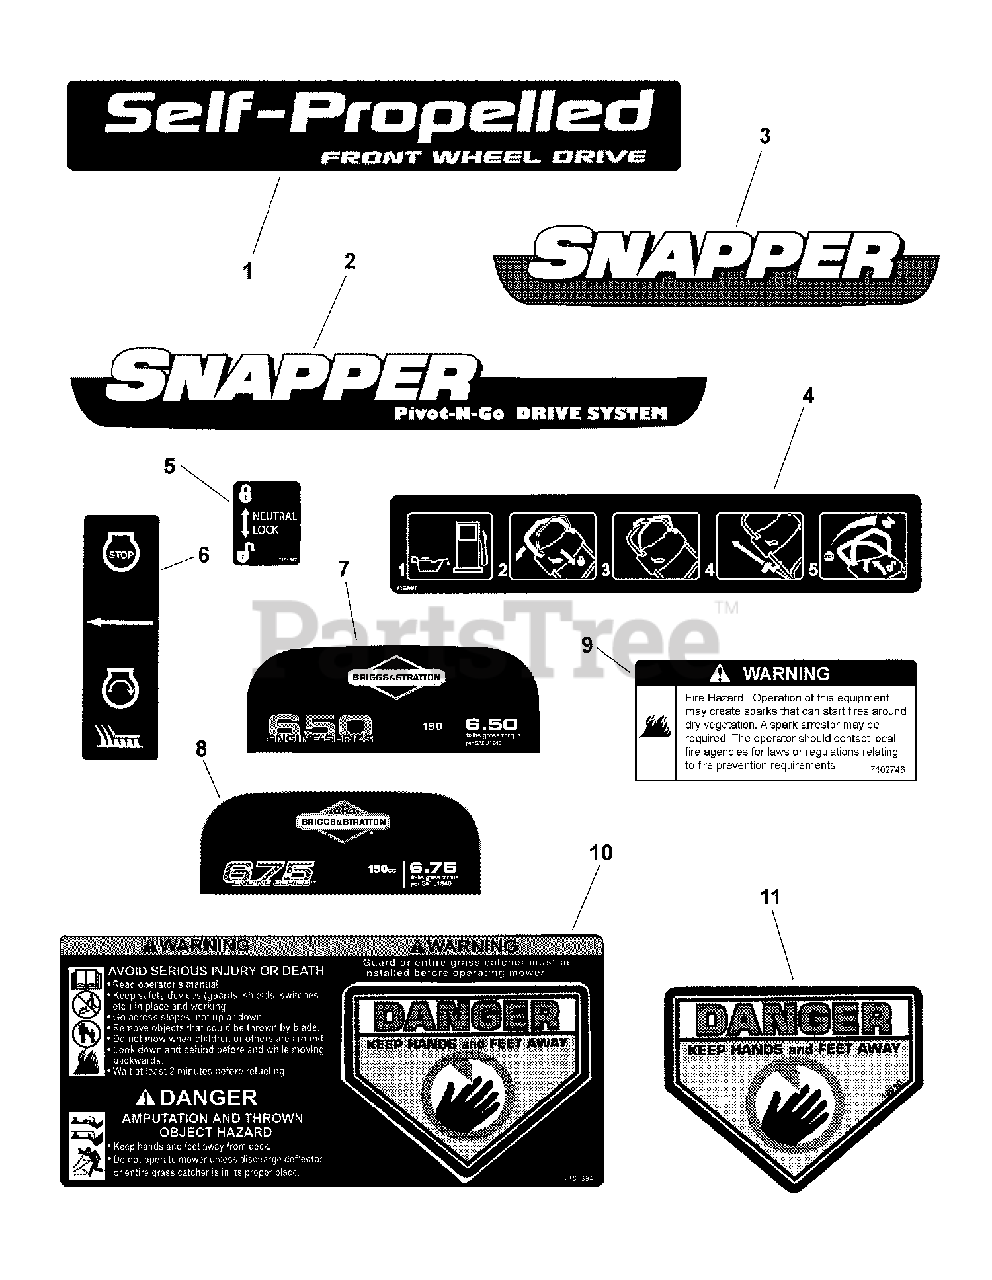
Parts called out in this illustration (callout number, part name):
1	DECAL, Front Cover, 22" Snapper, FWD
2	DECAL, Pivot-N-Go
3	DECAL, Briggs Engine, 675 Series
4	DECAL, Pivot Handle, Snapper
5	DECAL, Neutral Lock
6	DECAL, OPC Bail International Symbol
7	DECAL, Briggs Engine, 650 Series
8	DECAL, Briggs Engine, 675 Series
9	DECAL, Spark Arrestor
10	DECAL, Warning, Rear Discharge Door
11	DECAL, Danger, Cut Finger
